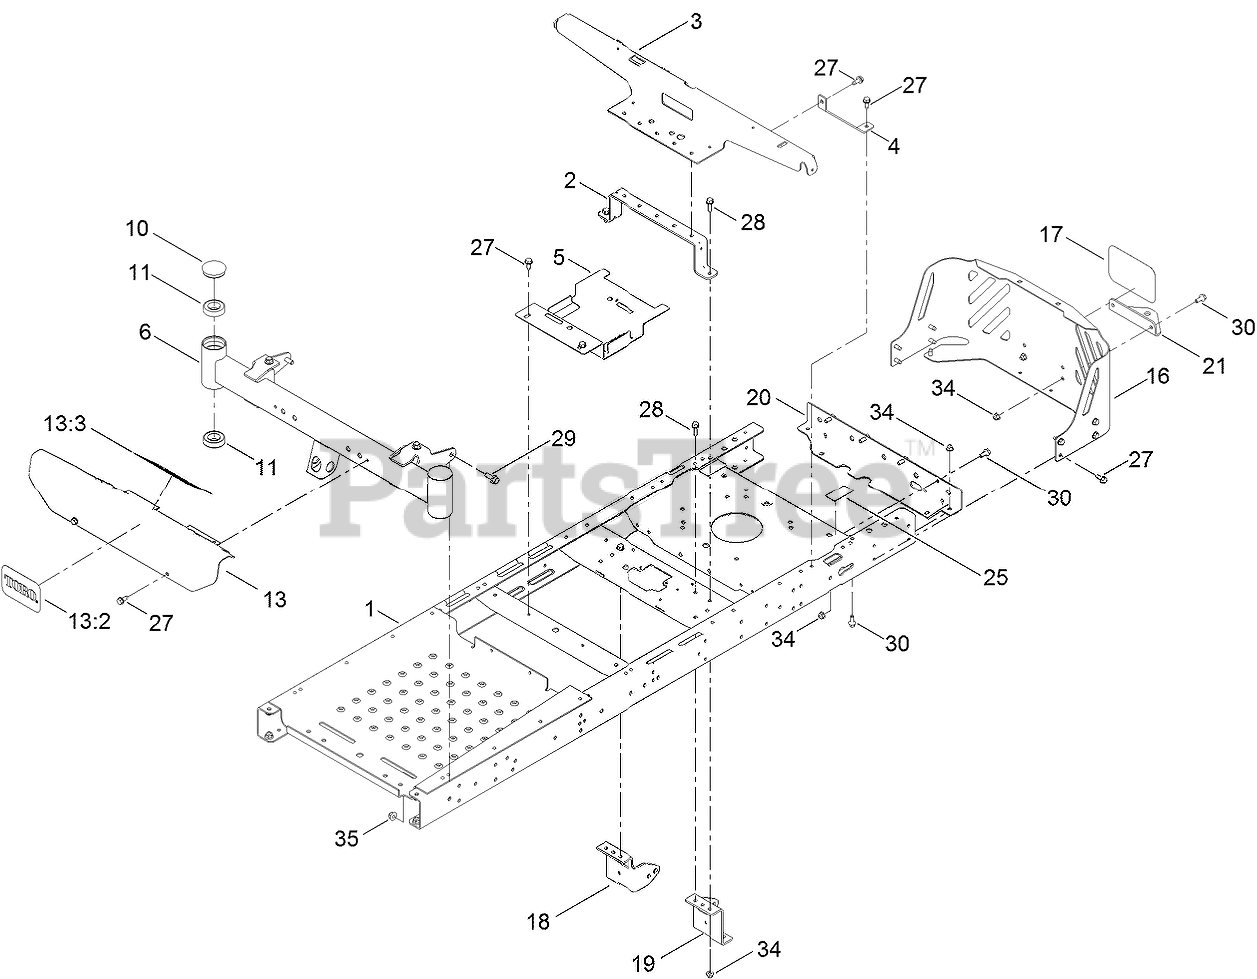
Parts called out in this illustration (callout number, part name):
1	FRAME ASM
2	BRACE-SEAT, REAR (NARROW)
3	SUPPORT-POD
4	SUPPORT-TANK, REAR
5	BRACKET-BATTERY
6	AXLE-FRONT, NARROW
10	CAP-GREASE
11	BEARING-BALL
13	FOOTREST ASM
13:3	DECAL-DANGER
16	GUARD-ENGINE, NARROW
17	DECAL
18	MOUNT-HYDRO, FRONT (RIGHT)
19	MOUNT-HYDRO, FRONT (LEFT)
20	CROSSMEMBER-REAR, NARROW
21	BRACKET-HITCH
25	DECAL-BYPASS
27	SCREW-HWHTF
28	SCREW-HHF
29	SCREW-HHF
30	SCREW-HHF
34	NUT-HF, NI
35	NUT-HF, NI
